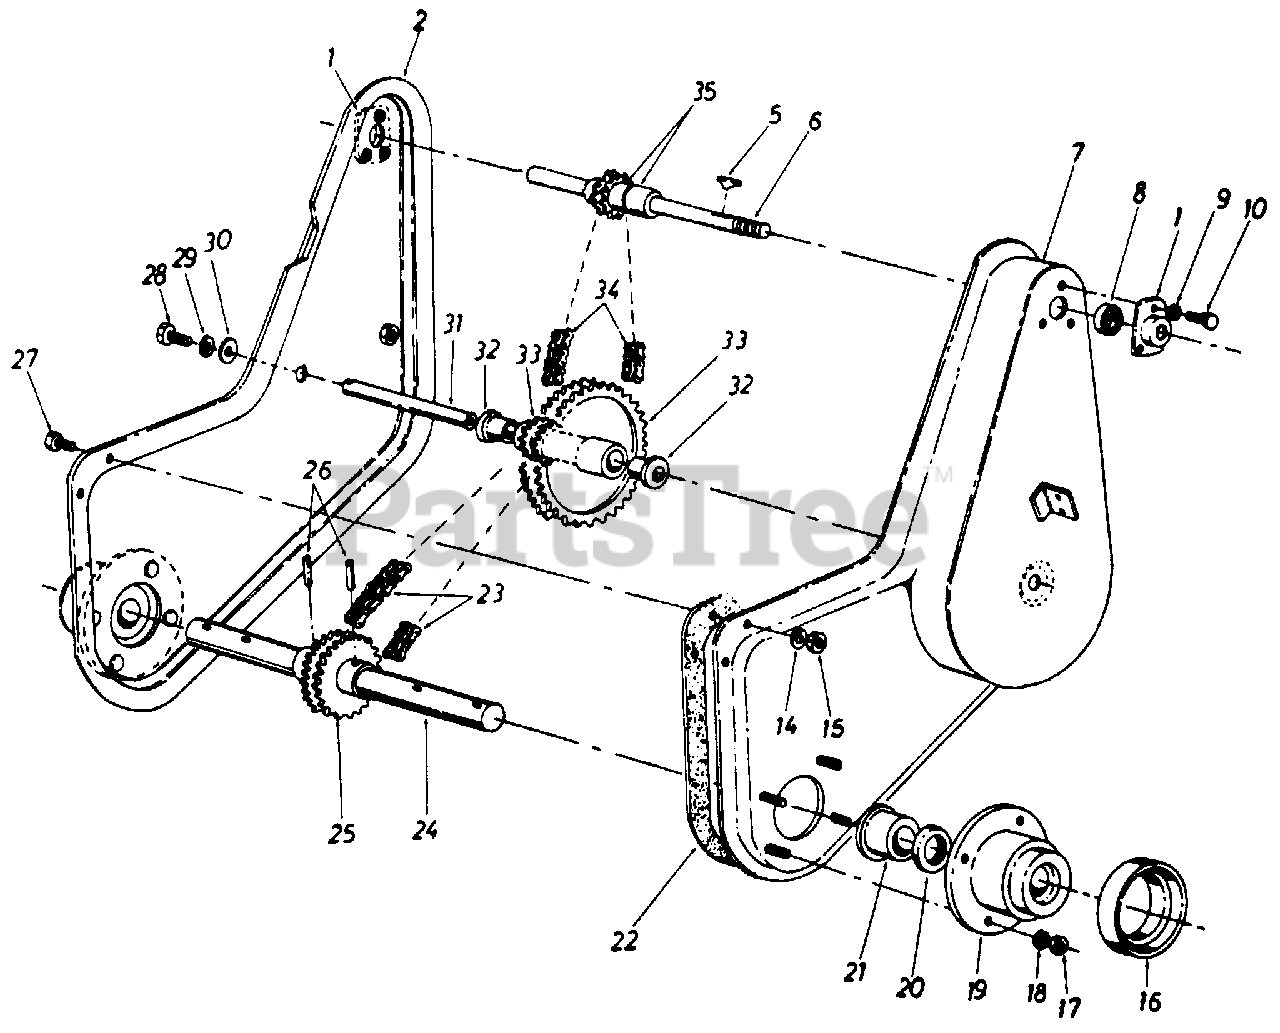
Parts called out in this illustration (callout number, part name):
1	Bearing Housing 1.375" Dia.
2	Housing Assembly R.H.
5	#6 Hi-Pro Key 5/32" x .62" Lg.
6	Input Shaft Assembly
9	L-Wash. 1/4" l.D.
10	Hex Bolt 1/4-20 x .62n Lg.
14	L-Wash. 1/4n l.D.
15	Hex Cent. L-Nut 1/4 20 Thd.
16	Dust Cap Cover
17	Hex Cent. L-Nut 5/16-18 Thd.
18	L-Wash. 5/16" l.D.
19	Cast Bearing Housing
20	Oil Seal
21	Flange Bearing 1.25n l.D. x 1 .75n O.D.
22	Gasket
23	Roller Chain #40-2 x 34.0" Lg.
24	Tine Shatt
25	Double Sprocket T24-2 Teeth l/2 Pitch
26	Spiral Pin 3/8 Dia. x 2.00" Lg.
27	Hex Bolt 1/4-20 x .62" Lg.
28	Hex Bolt 5/16-18 x .75" Lg.
29	L-Wash. 5/16" I.D.
30	Fl-Wash. 5/16" I.D.
31	Sprocket Shan
32	Flange Bearing .62" I.D. x .75 O.D.
33	Double Sprocket Assembly
34	Roller Chain #35-2 x 36.75"
35	Spacer 5/8" I.D. x 7/8 O.D.
